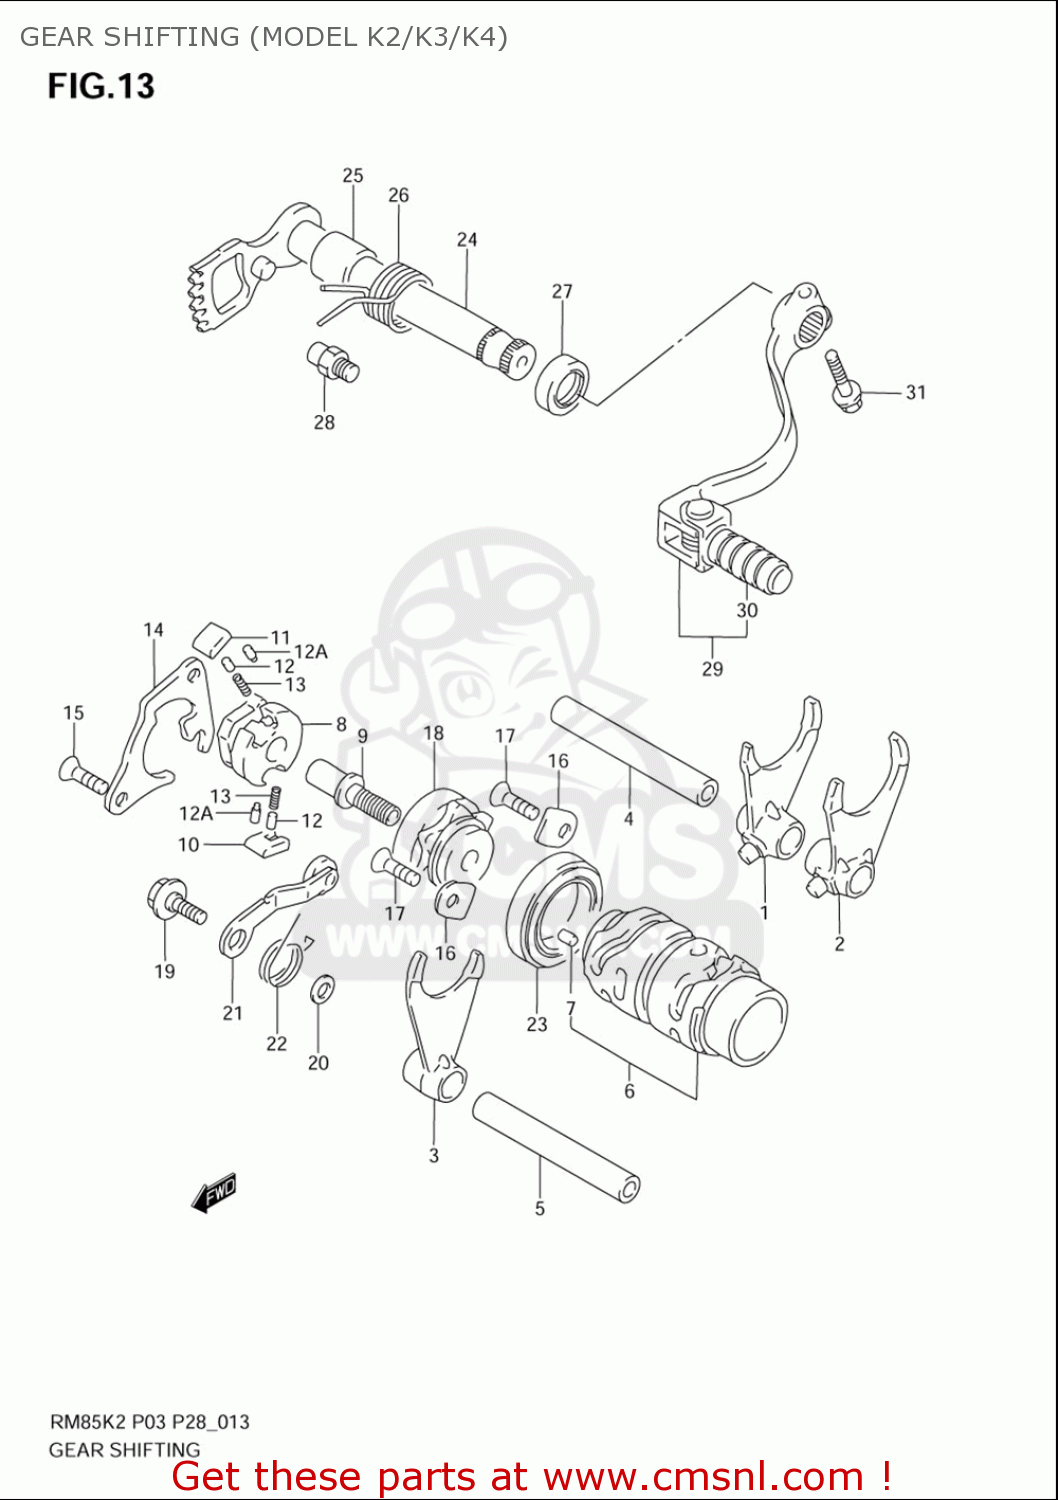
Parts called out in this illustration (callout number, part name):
1	FORK,GEAR SHIFT NO.1
2	FORK,GEAR SHIFT NO.2
3	FORK,GEAR SHIFT NO.3
4	SHAFT,GEAR SHIFT FORK NO.1
5	SHAFT,GEAR SHIFT FORK(L:60)
6	CAM,GEAR SHIFT
7	PIN
8	GEAR,GEAR SHIFT CAM DRIVEN
9	PIN,SHIFT CAM DRIVEN GEAR
10	PAWL,GEAR SHIFT NO.1
11	PAWL,GEAR SHIFT NO.2
12	PIN(5X8)
12A	PIN
13	SPRING
14	LIFTER,GEAR SHIFT POLE
15	SCREW
16	RETAINER,COUNTER BEARING,R
17	SCREW
18	PLATE,SHIFT CAM STOPPER
19	BOLT(6X14.3)
20	WASHER
21	STOPPER,SHIFT CAM
22	SPRING
23	BEARING
24	SHAFT,GEAR SHIFT
25	SPACER(14X20X17.5)
26	SPRING
27	SEAL,OIL(14X22X6)
28	STOPPER,GEAR SHIFT ARM
29	LEVER ASSY,GEAR SHIFT
30	RUBBER,GEAR SHIFT PEDAL
31	BOLT,6X20
